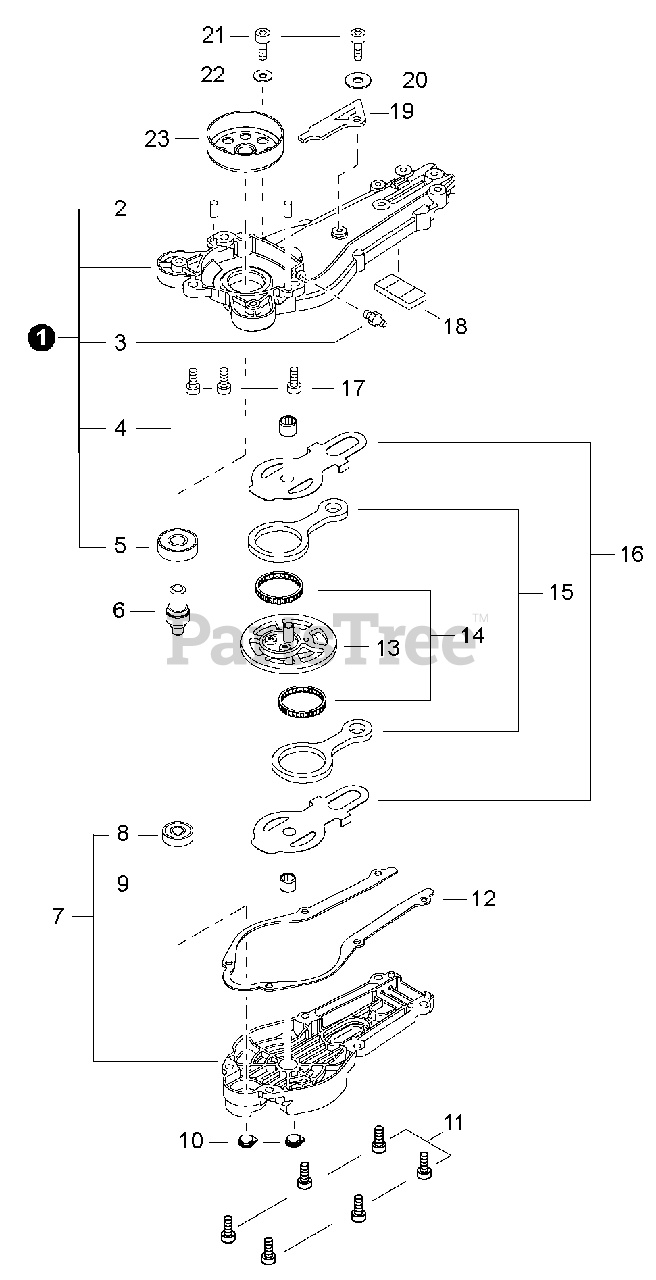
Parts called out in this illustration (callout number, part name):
1	GEAR CASE HOUSING ASSY
2	PIN, LOCATING 4×8
3	FITTING, GREASE
4	BEARING, NEEDLE 8
5	BEARING, BALL 6001 DDU
6	SHAFT, PINION
7	COVER ASSY, GEAR CASE
8	BEARING, BALL 608ZZ
9	BEARING, NEEDLE 8
11	BOLT, TORX 5×16
12	GASKET, GEAR CASE
13	GEAR, SPUR
14	BEARING, NEEDLE 30
16	PLATE, SIDE
17	BOLT, TORX 6×20
18	PACKING, FELT
19	CUSHION
20	WASHER 5
21	BOLT, TORX 5
22	WASHER 5.3×10×1
23	DRUM, CLUTCH
